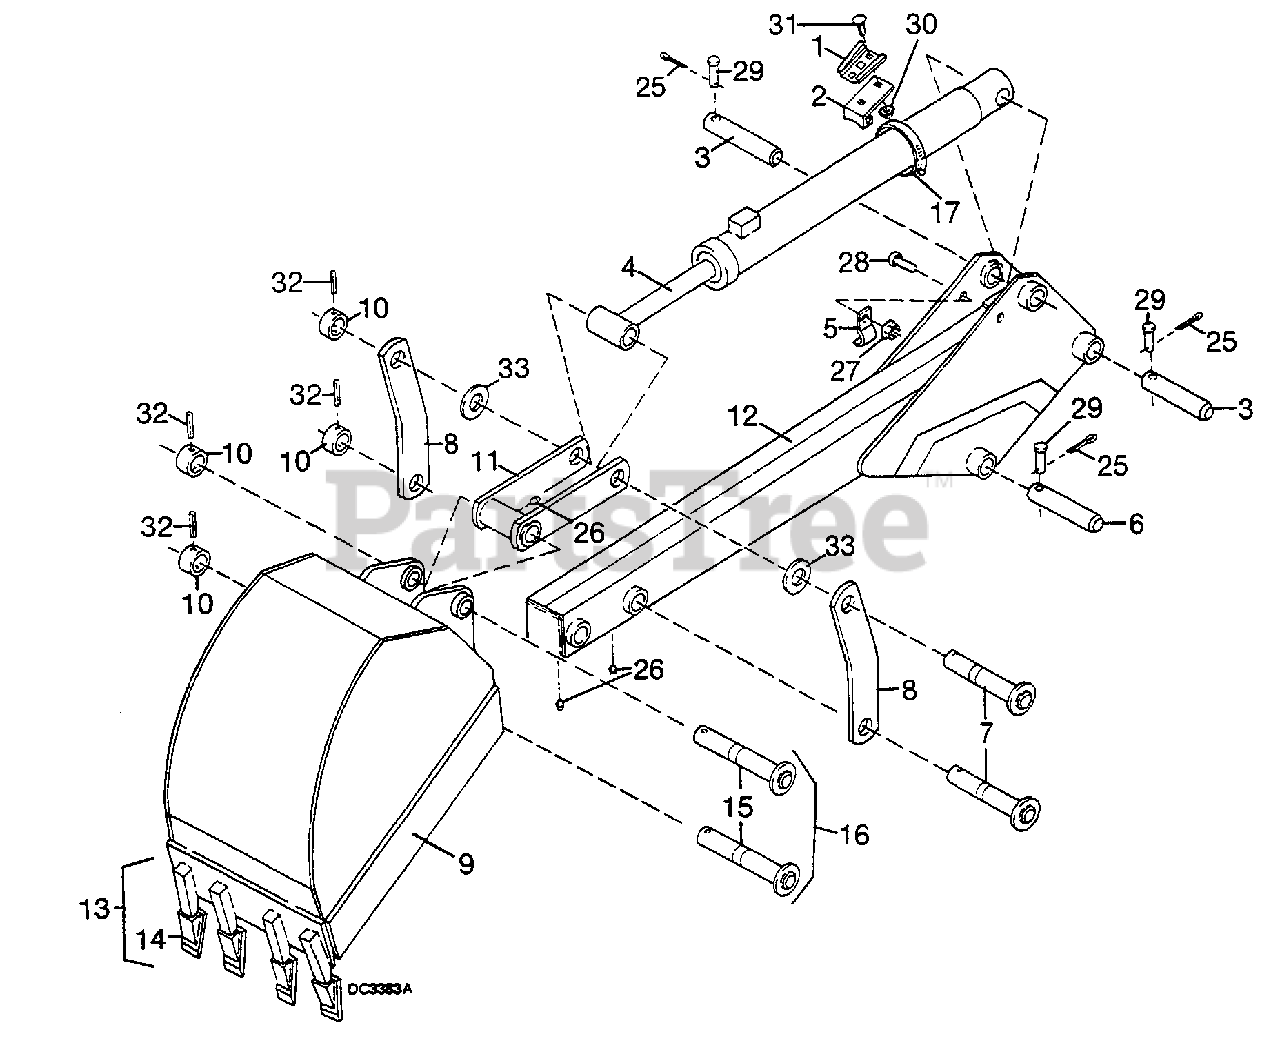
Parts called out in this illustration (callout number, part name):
1	Socket, SMV emblem
2	Bracket, SMV socket
3	Pin, Pivot 4-7/8 x 1"
4	2 x 16-3/4 Hydraulic cylinder
5	Hose clamp
6	Pivot pin, Boom 8-1/2 x 1"
7	Rotating pivot pin 6 x 1"
9	8" Standard bucket
9	12" Standard bucket
9	12" Hvy-duty bucket
9	16" Standard bucket
9	16" Hvy-duty bucket
9	18" Standard bucket
9	18" Hvy-duty bucket
9	24" Hvy-duty bucket
10	Pivot pin retaining sleeve
11	Bucket arm
12	Dipperstick assembly
13	Shank & tooth asy
13	Shank & tooth asy 2/0
14	Tooth
14	Tooth 2/0
15	Pivot Pin assembly, 1.0 x 7.25
16	HD Pin Kit
17	Hose clamp
25	1/16 x 1/2 Cotter pin
26	1/4-28 Taper thread grease fitting
27	1/4 NC Flanged hex locknut
28	1/4 NC x 3/4 Hex head cap screw GR5
29	1/4 x 1-7/8 Clevis pin
30	5/16 NC Flanged hex locknut
31	5/16 NC x 1/2 Carriage bolt
32	5/16 x 1-3/4 Spirol pin
33	1" SAE Flat washer
